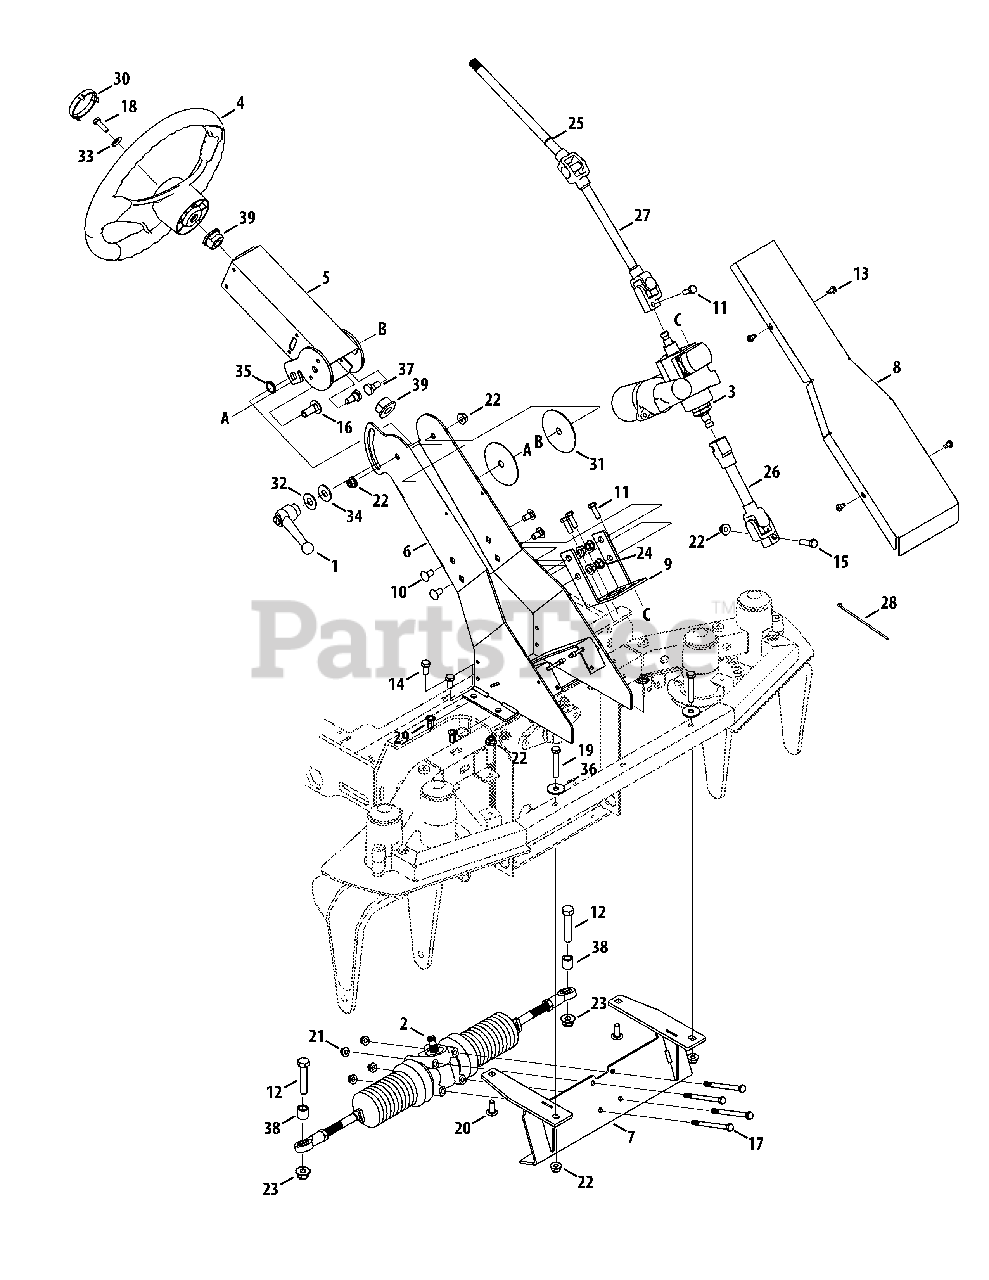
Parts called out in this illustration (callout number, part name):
1	Steering Column Adjustment Lever
2	Steering Gearbox
2	Ball Joint
3	Power Steering Arm
3	Module, EPS Control
4	Steering Wheel
5	Upper Column
6	Base Column
7	Steering Rack Mount
8	Front Column Cover
9	Power Steering Mount
10	Carriage Bolt
11	Hex Cap Screw
12	Hex Cap Screw
14	Hex Cap Screw
15	Hex Cap Screw
16	Carriage Bolt
17	Hex Cap Screw
18	Hex Cap Screw
19	Hex Cap Screw
20	Carriage Bolt
21	Nut, Flangelock
22	Nut, Flangelock
23	Nut, Flangelock
24	Nut, Flangelock
25	Retainer Ring
26	Steering Shaft
27	Steering Shaft
28	Cable Tie
29	Rivet
31	Column Wear Plate
32	Washer
33	Bevel Washer
35	Lock Washer
37	Shoulder Bolt 3/8-16
39	Flange Bearing
